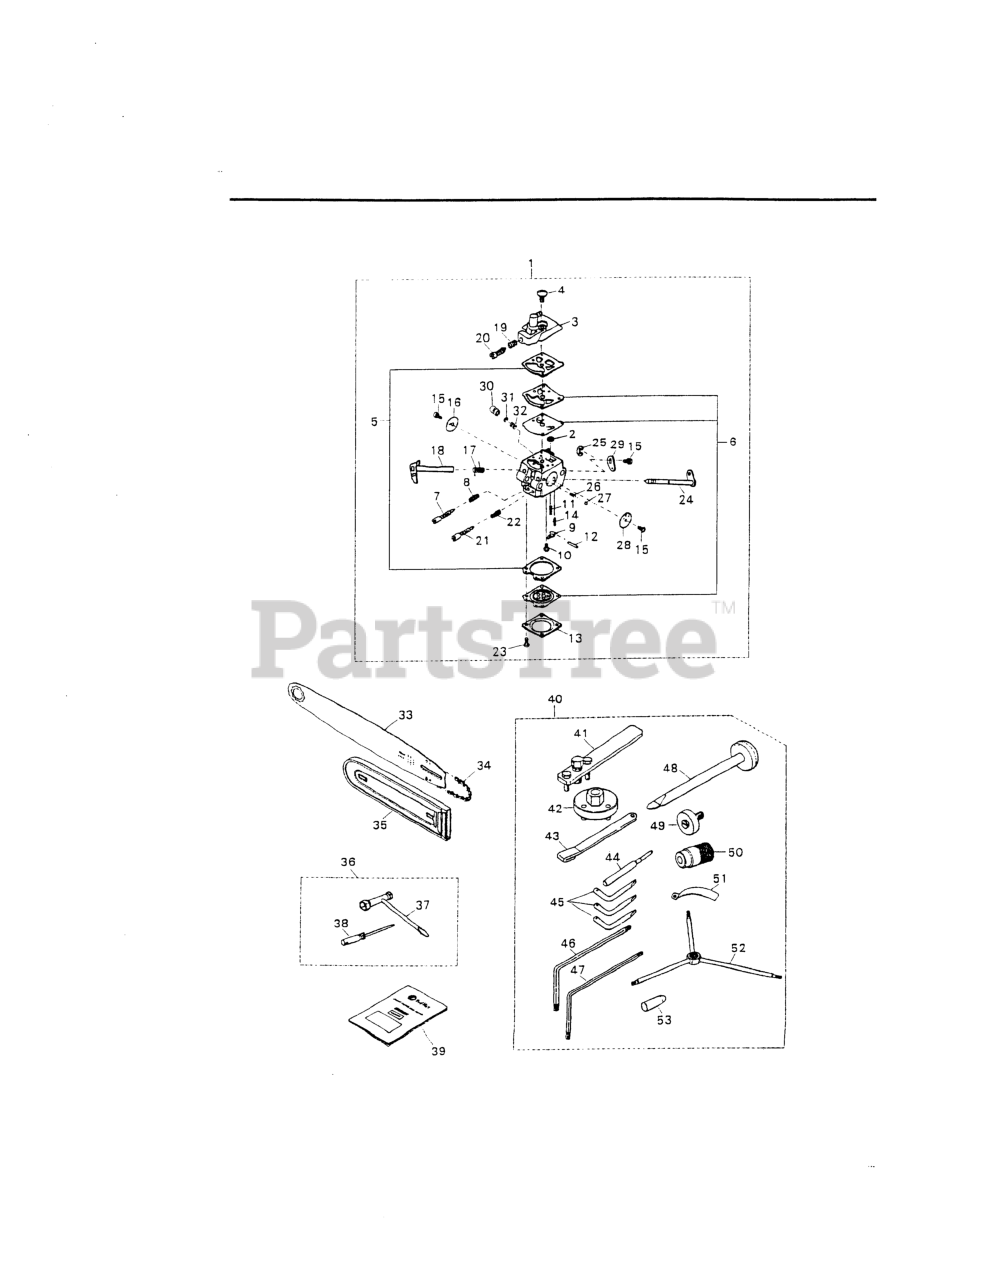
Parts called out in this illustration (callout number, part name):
1	CARBURETOR-A (WT-296-1)
3	COVER ASSEMBLY
5	KIT ONLY
6	DIAPHRAGM KIT
7	L-NEEDLE
9	LEVER
11	KIT ONLY
12	PIN, METERING LEVER
14	VALVE, INLET
16	VALVE, THROTTLE
17	SPRING, RETURN
18	SHAFT, THROTTLE
19	SPRING, IDLE
21	HIGH SPEED NEEDLE
23	SCREW ASSEMBLY
24	SHAFT, CHOKE
26	SPRING
27	BALL, FRICTION
28	VALVE, CHOKE
33	BAR 16
34	CHAIN
36	TOOL SET
37	WRENCH, PLUG
38	SCREWDRIVER
40	TOOL SET
41	PULLER ASSY
42	WRENCH (TOOL)
43	STOPPER (TOOL)
44	GUIDE (TOOL)
45	WRENCH (TOOL)
46	WRENCH (TOOL)
47	WRENCH (TOOL)
48	GUIDE (TOOL)
49	GUIDE (TOOL)
50	HOLDER (TOOL)
51	GUAGE, AIR GAP (TOOL)
53	GUIDE (TOOL)
